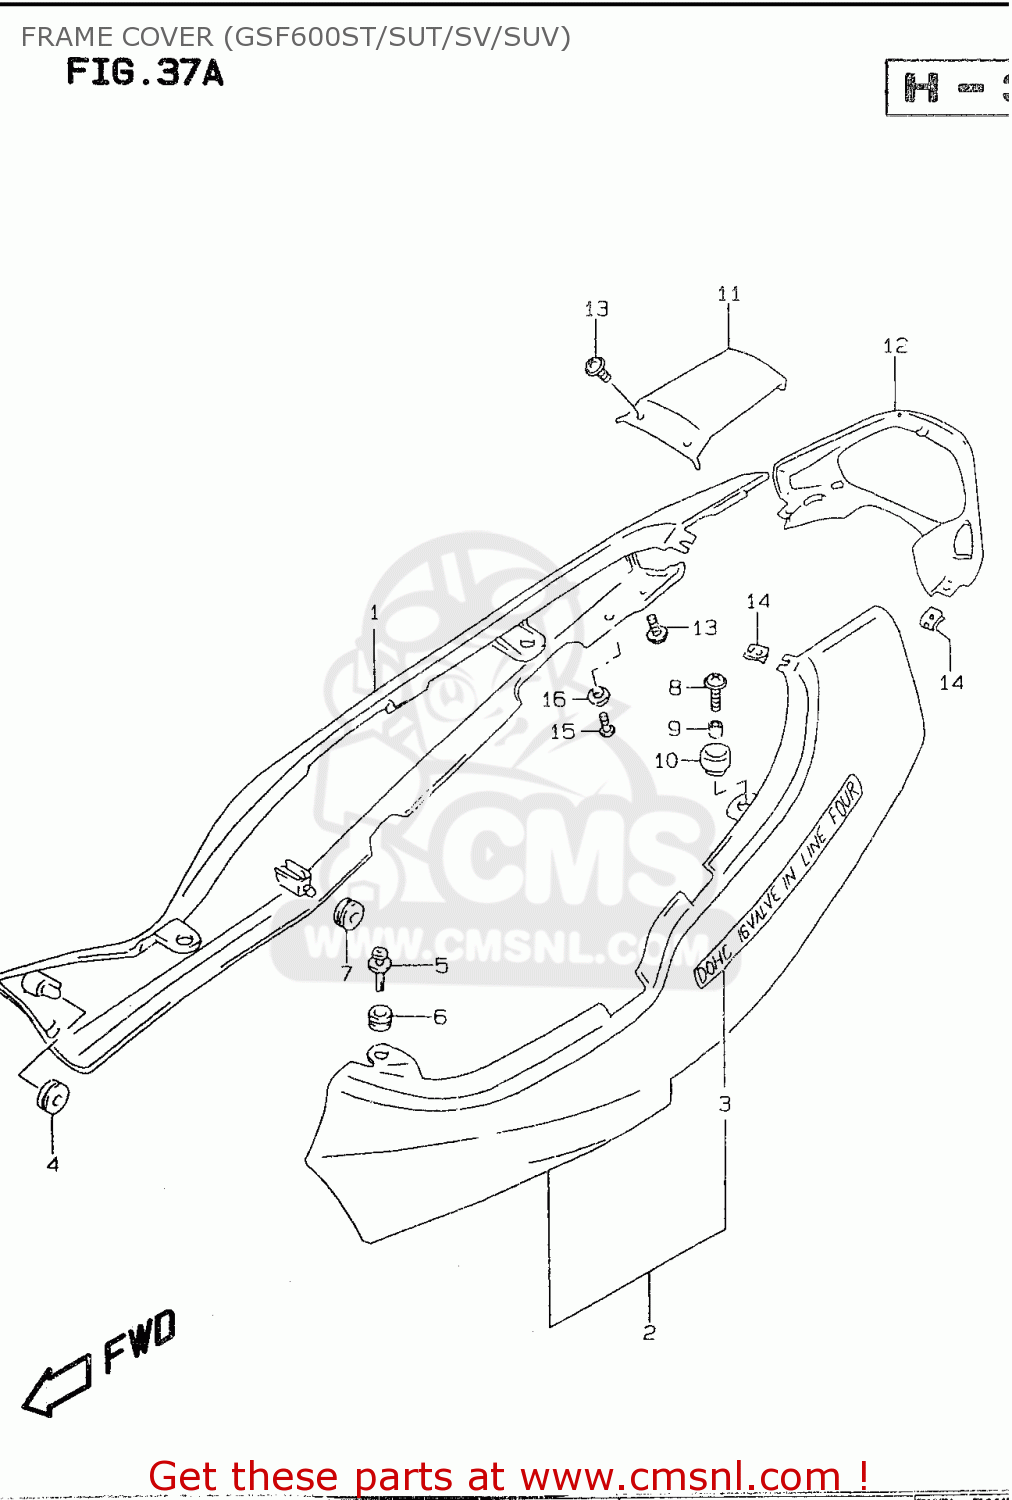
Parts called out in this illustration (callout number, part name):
1	COVER,FRAME,R(GREEN)
2	COVER,FRAME,L(GREEN)
3	EMBLEM,FRAME COVER
4	CUSHION,FRAME COVER FR
5	CLIP
6	CUSHION
7	CUSHION
8	SCREW(6X20)
9	SPACER(6.5X10X9.4)
10	CUSHION
11	COVER,FRAME CTR
12	COVER,FRAME RR
13	SCREW
14	NUT
15	SCREW
16	WASHER(6.3X16X1.5)
